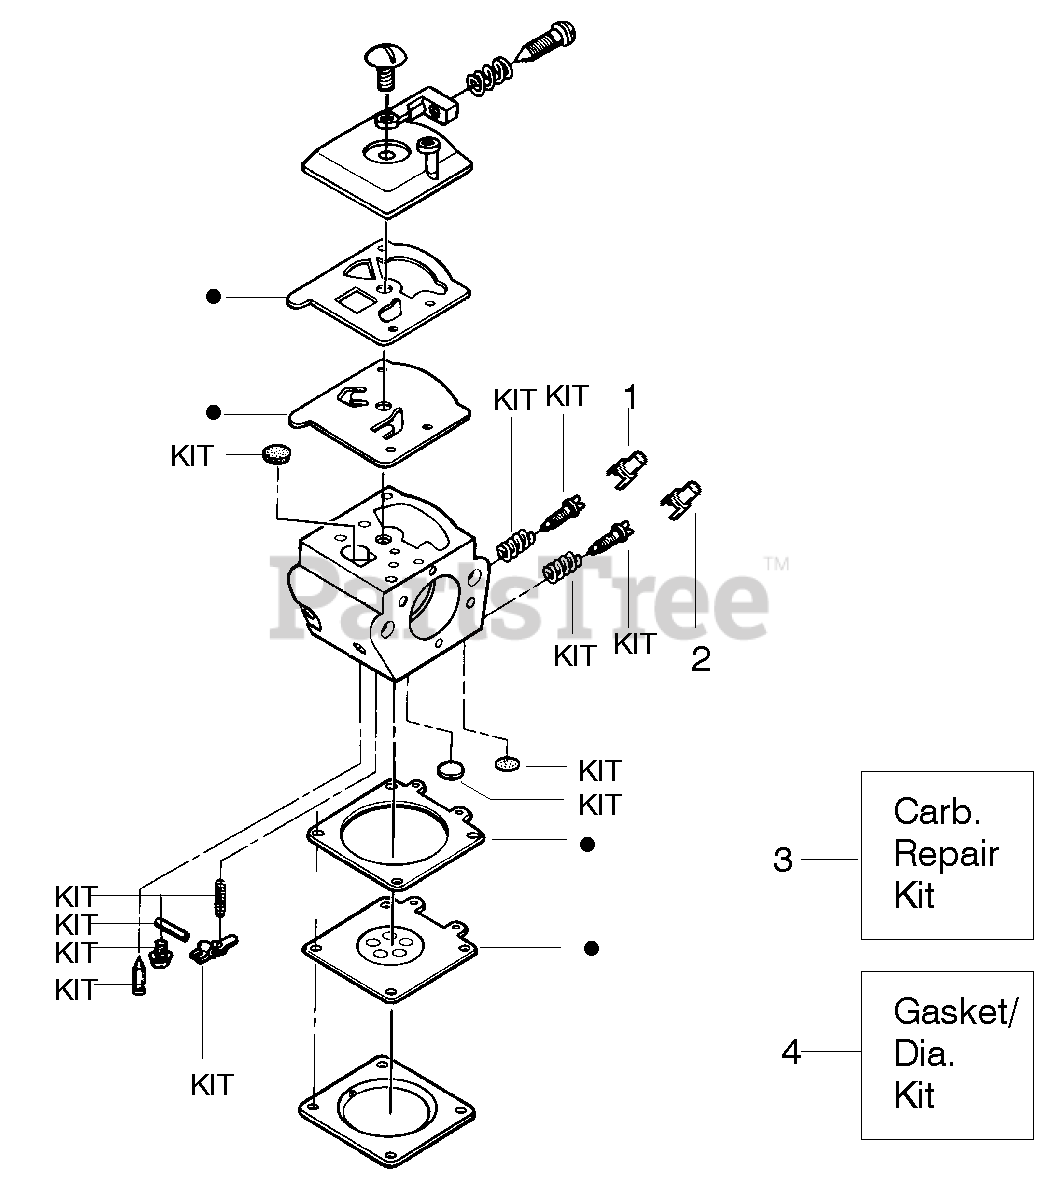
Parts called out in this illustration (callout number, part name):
1	Limiter Cap-High (brown)
2	Limiter Cap-Low (tan)
3	Carburetor Repair Kit (KIT= Indicates Contents) Walbro (WT391)
4	Gasket Diaphragm Kit Walbro (WT391)
